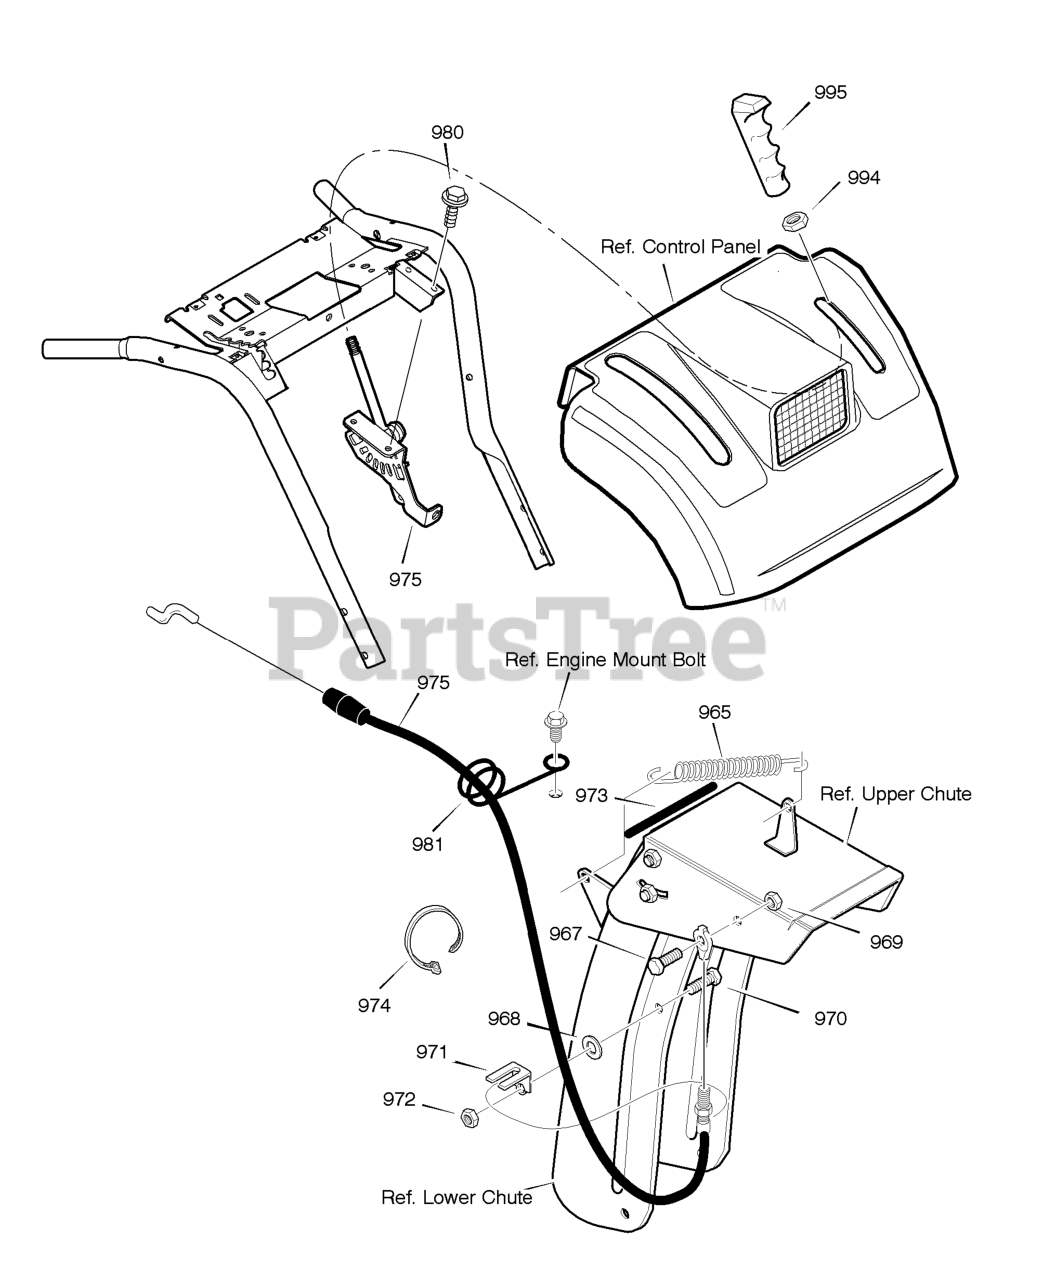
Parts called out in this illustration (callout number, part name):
965	TENSION SPRING
967	BOLT, SHOULDER
968	FLATWASHER
970	SCREW, 5/16-18 x 0.75
971	BRACKET, CABLE CHUTE
972	NUT, 5/16-18
973	TRIM STRIP, BLACK
974	TIE, CABLE
975	CABLE, CHUTE DEFLECTOR
981	WIRE FORM, CHUTE CABLE
994	NUT, 3/8-16
995	KNOB, SHIFT
